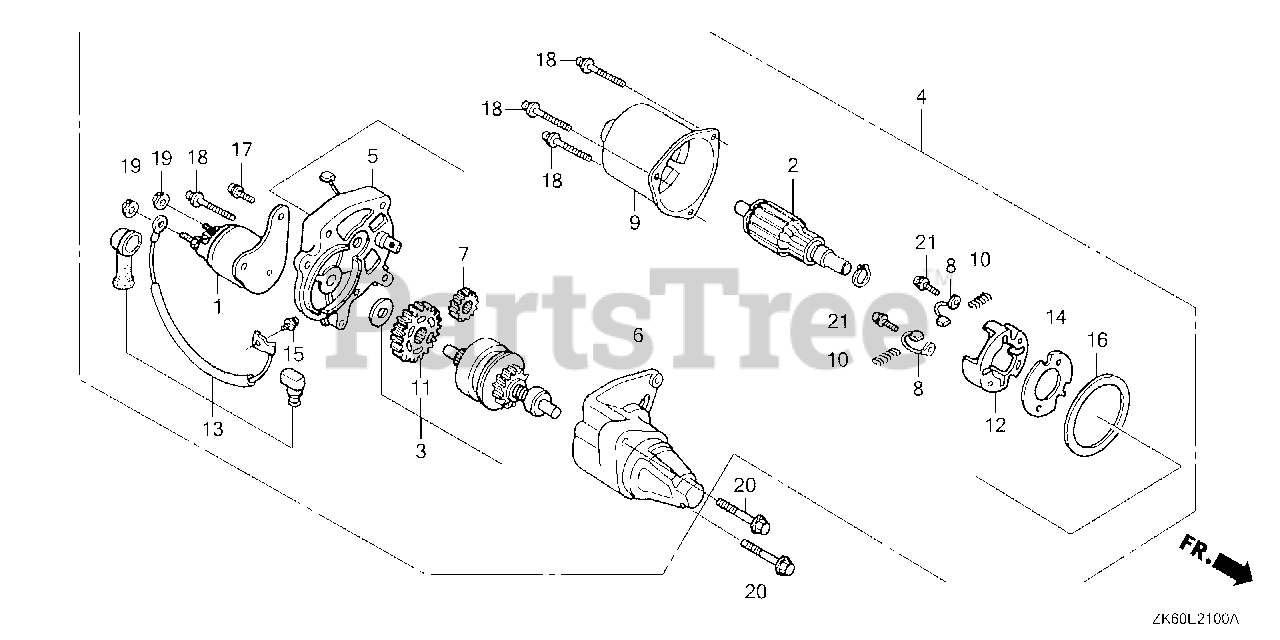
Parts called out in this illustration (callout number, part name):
1	CONTACTOR ASSY.
3	CLUTCH, OVERRUNNING
4	STARTER MOTOR UNIT
5	BRACKET, CENTER
6	BRACKET, FR.
7	GEAR, DRIVE PINION
10	SPRING, BRUSH RETURN
11	GEAR, REDUCTION
12	HOLDER, BRUSH
13	WIRE, WATER COVER
15	SCREW-WASHER (4X6)
17	BOLT-WASHER (5X14)
18	SCREW-WASHER (5X32)
19	NUT-WASHER (6MM)
20	BOLT, FLANGE (8X35)
